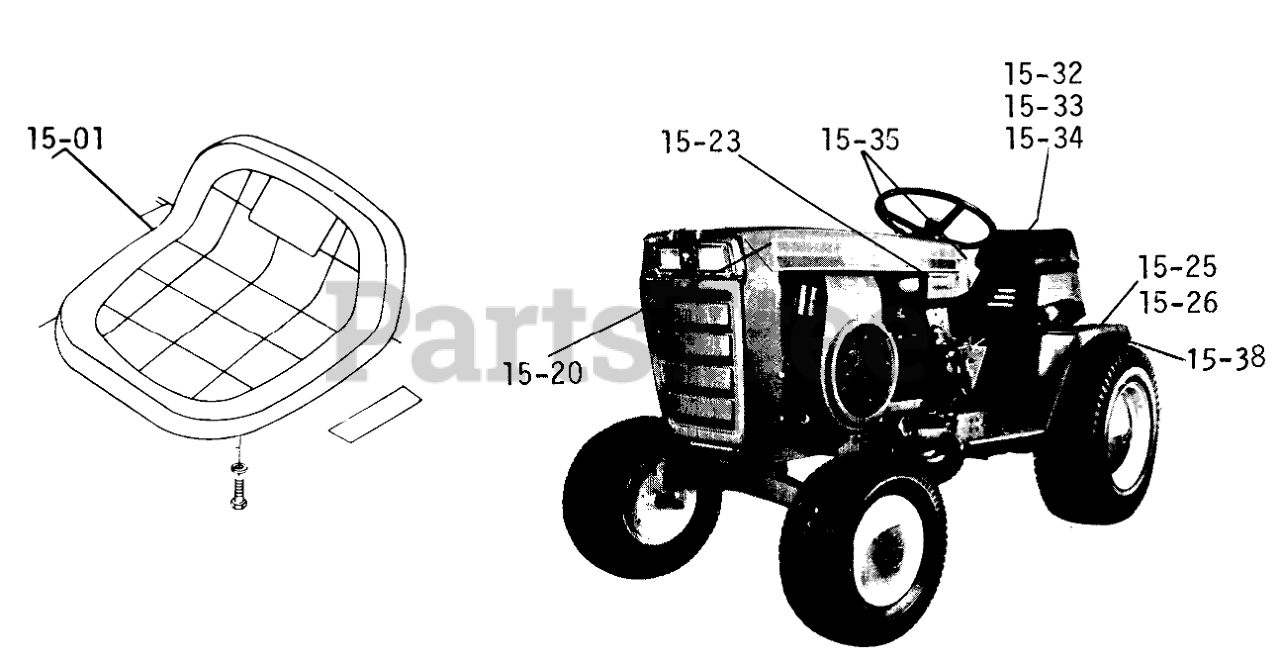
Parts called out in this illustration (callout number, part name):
15-01	Bolt Hex 5/16-18
15-01	Lockwasher
15-23	Decal-Model
15-26	Reflector
15-34	Washer
15-35	DECAL-HAND LIFT
15-35	Decal-Read Manual
